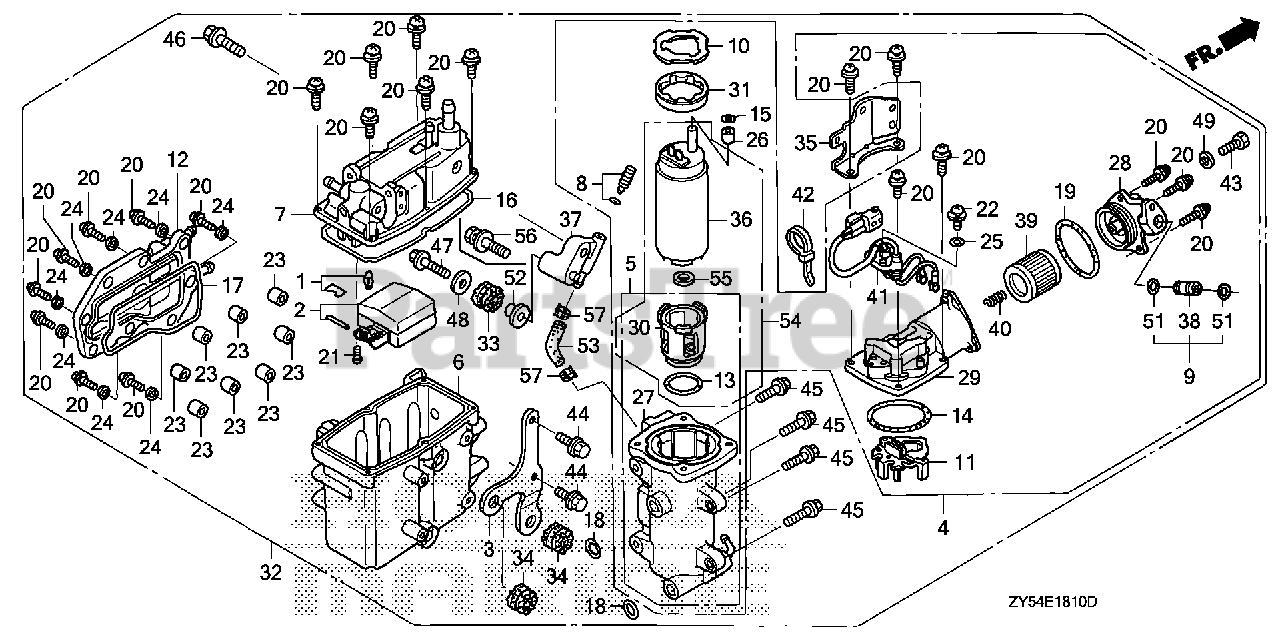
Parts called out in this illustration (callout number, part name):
1	VALVE SET, FLOAT
3	STAY A, PLATE
4	PUMP UNIT, FUEL (MSDS)
4	PUMP UNIT, FUEL
6	BODY, CHAMBER
7	COVER
8	SCREW SET, DRAIN (CARBURETOR NO.)
12	COVER, WATER JACKET
15	O-RING
15	O-RING (7.3X2.2) (NOK)
20	SCREW-WASHER
21	SCREW, PAN
22	SCREW, WASHER
23	COLLAR, SET
24	WASHER, PLAIN
25	WASHER, PLAIN
27	CASE, PUMP
28	COVER B, PUMP
29	COVER, PUMP (A) (NOT AVAILABLE)
29	COVER, PUMP (A)
30	INSULATOR
32	SEPARATOR ASSY., VAPOR
32	SEPARATOR ASSY., VAPOR (NOT AVAILABLE)
33	GROMMET, VAPOR SEPARATOR
34	GROMMET, VAPOR SEPARATOR
35	STAY, PLATE
36	PUMP UNIT, FUEL (MSDS)
37	STAY, VAPOR SEPARATOR
38	JOINT, FUEL PIPE
39	SCREEN, FUEL STRAINER
40	SPRING, SET
43	BOLT, SEALING (6MM)
44	BOLT, FLANGE (6X16)
45	BOLT, FLANGE (6X25)
46	BOLT, FLANGE (8X30)
47	BOLT, FLANGE (8X35)
48	WASHER, PLAIN (8MM)
49	WASHER, SEALING (6MM)
51	O-RING (7.8X1.9) (ARAI)
52	COLLAR (8.5X14.5)
53	TUBE F, FUEL
54	PUMP UNIT, FUEL (B) (MSDS)
56	BOLT-WASHER (8X35)
57	CLAMP, TUBE (8.0)
